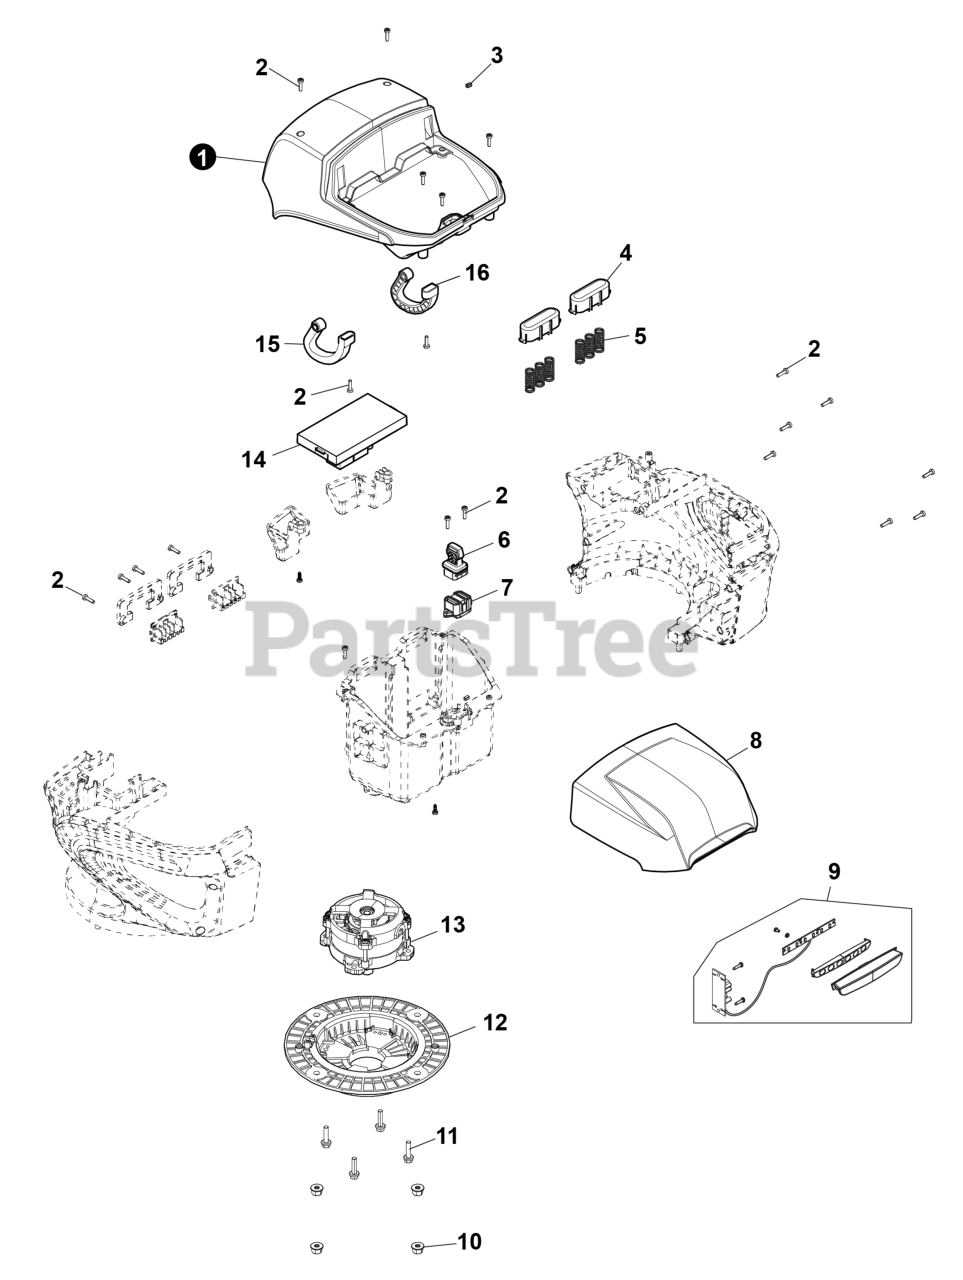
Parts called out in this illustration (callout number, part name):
1	COVER, UPPER
3	PLUG, RUBBER
4	COVER, BATTERY SPRING
7	SWITCH, KEY
8	COVER, BATTERY
9	LIGHT ASSY, LED
12	COVER,MOTOR
